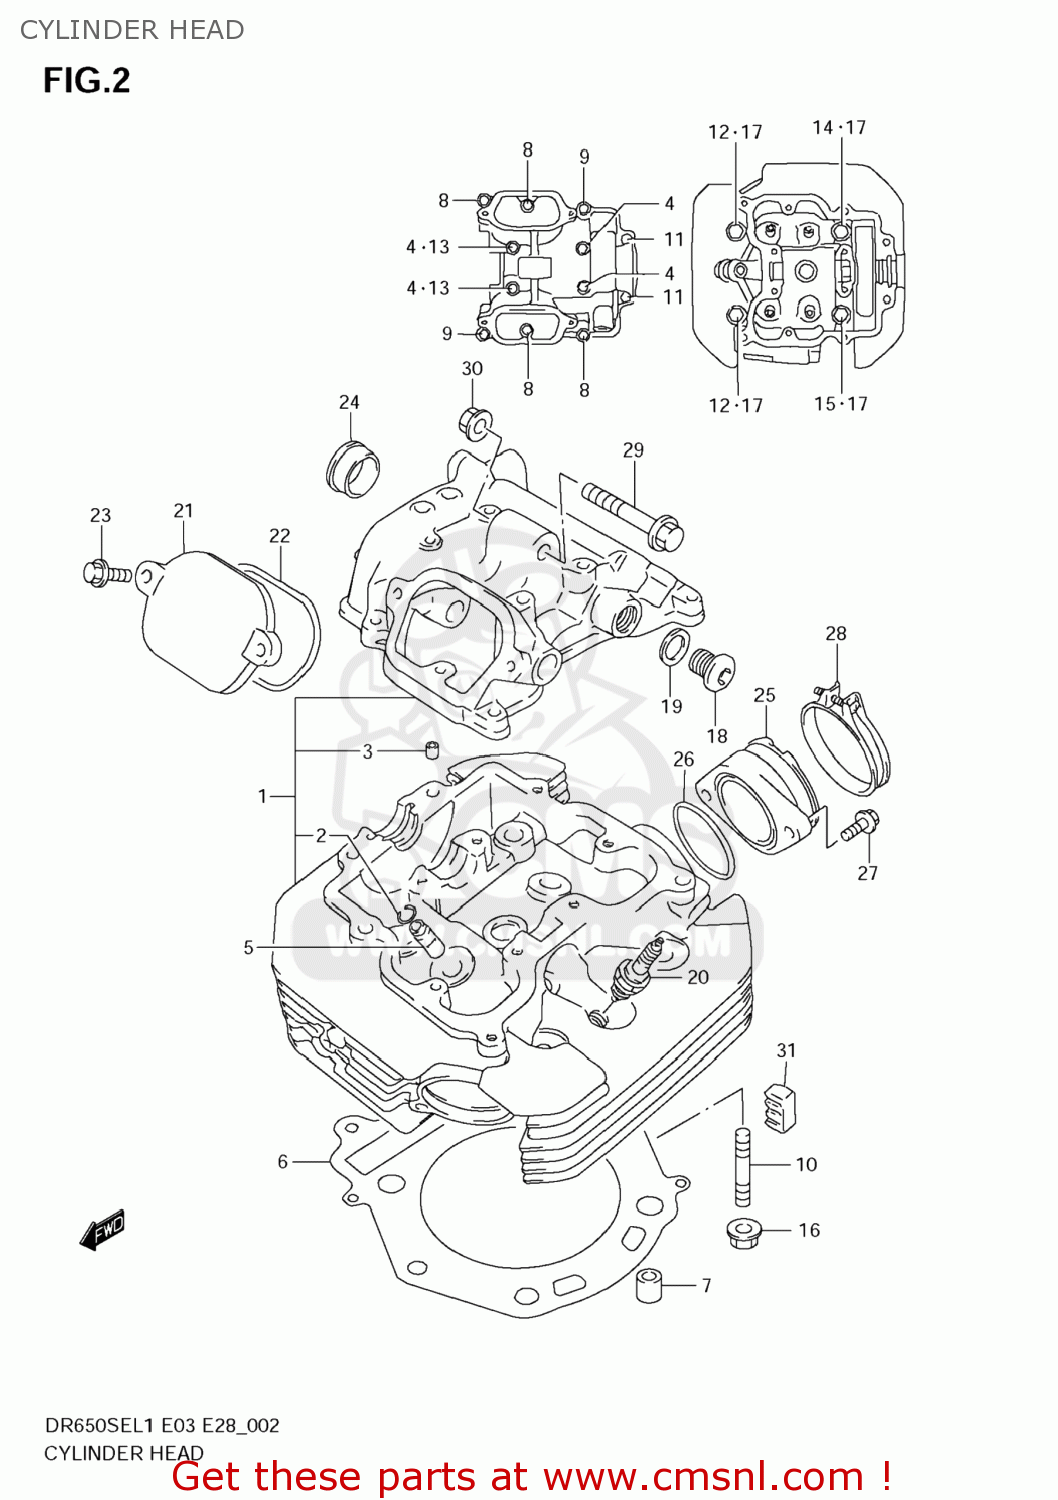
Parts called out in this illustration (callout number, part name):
1	HEAD ASSY,CYLINDER
2	RING,SNAP
3	PIN(6.2X8X11)
4	BOLT(6X55)
5	GUIDE,VALVE
6	GASKET,CYLINDER HEAD
7	PIN
8	BOLT
9	BOLT
10	BOLT,STUD
11	BOLT(6X115)
12	BOLT(10X180)
13	GASKET(5.8X13X1.2) (NAS)
14	BOLT(10X190)
15	BOLT(10X200)
16	NUT
17	GASKET(10.5X22X2) (NAS)
18	PLUG,14X12
19	GASKET(13.8X18.8X4.8) (NAS)
20	PLUG,SPARK(CR10E)
21	CAP,INSPECTION
22	O RING,INSPECTION CAP
23	BOLT
24	PLUG,OD:30
25	PIPE,INTAKE
26	O RING(D:2.4,ID:45.7)
27	SCREW(6X16)
28	CLAMP
29	BOLT(8X53)
30	NUT
31	PAD,CYLINDER HEAD RUBBER
